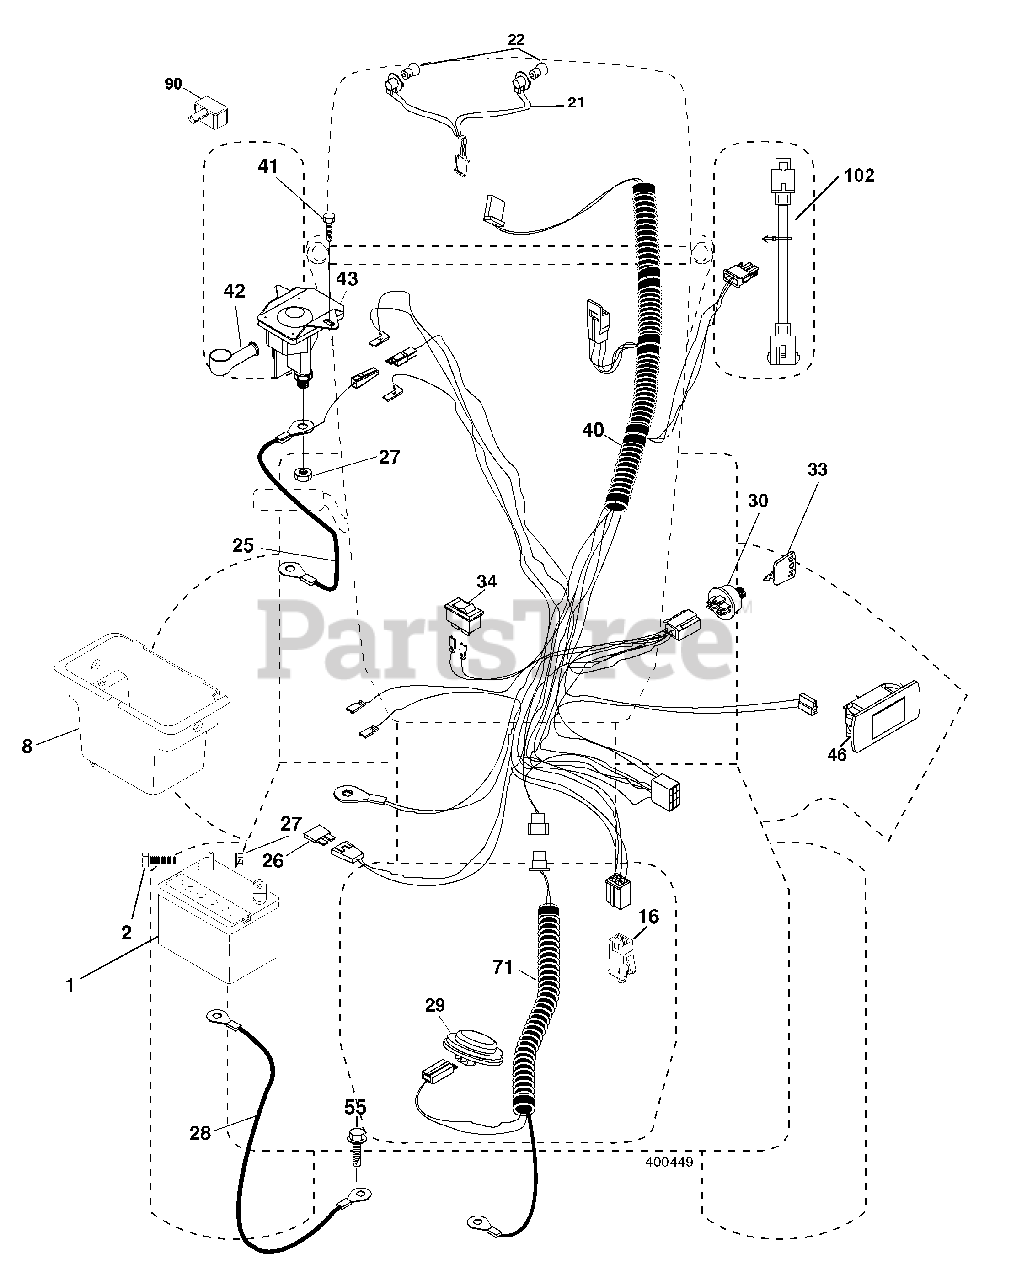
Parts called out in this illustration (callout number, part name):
1	Battery
2	Bolt Hex Head 1/4-20 x 3/4
8	Box Battery
16	Switch Interlock Push-In
21	Harness Socket Light W/4152J
22	Bulb Light
25	Cable Starter
27	Nut Keps Hex 1/4-20 unc
28	Cable, Ground
29	Switch, Seat
30	Switch, Ign
33	Key, Ignition
34	Switch Light / Reset
40	Harness Ign.
41	Screw Thd Cut 1/4-20 x 1/2
42	Cover, Terminal
43	Solenoid
46	Gauge Hourmeter
55	Screw Thdrol 5/16-18 x 3/4 TYTT
71	Harness Ign. Dash
90	Cover Terminal
102	Harness Pigtail
